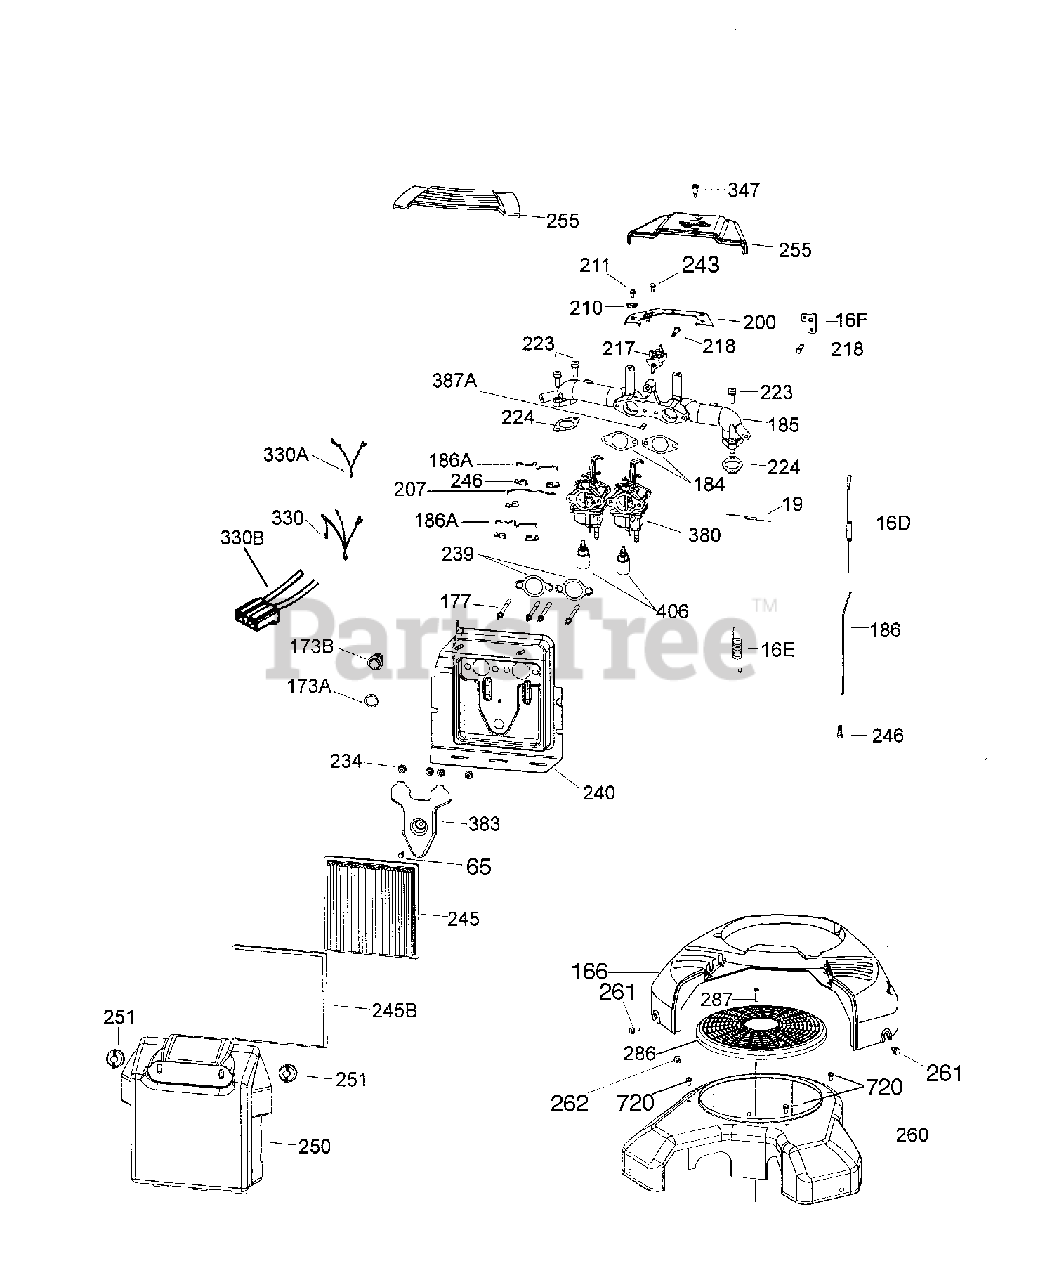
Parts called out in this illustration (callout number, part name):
11B	Screw, 10-32 x 7/16"
15B	Screw, 1/4-20 x 5/8"
16D	Governor Spring, Hi-speed
16E	Governor Idle Spring
16F	Bell Crank Lever
19	Throttle Spring
37	Lock Nut, 1/4-20
41	Piston & Pin Ass'y. (Std.) (Incl. 43)
41	Piston & Pin Ass'y.(.010"OS)(Incl.43)
72B	Oil Drain Plug
173A	Breather Tube Grommet
173B	Breather Tube Fitting
177	Carbuertor Mounting Stud
184	* Carburetor to Intake Pipe Gasket
185	Intake Pipe (Incl. 387A)
186	Governor Link
186A	Choke Link
200	Control Bracket
207	Throttle Link
210	Conduit Clip
211	Screw, 10-32 x 3/8"
217	Control Lever
218	Screw, 10-32 x 1-1/4"
223	Screw, T-30, 5/16-18 x 7/8"
224	* Intake Pipe Gasket (Pipe to Head)
234	Lock Nut, 1/4-20
238	Screw, 10-32 x 7/16"
239	* Air Cleaner Gasket
240	Air Cleaner Body Ass'y. (Incl. 239)
245	Air Cleaner Filter (Paper)
245B	Air Cleaner Pre-Filter (Poly)
246	Connector Bushing Link
250	Air Cleaner Cover
251	Wing Head Screw, 1/4-20 x 1-19/32"
255	Control Cover
260	Blower Housing (Red)
261	Screw, 1/4-20 x 1/2"
286	Flywheel Screen
287	Screw, T-20 8-18 x 1-15/32"
290	Fuel Line (16.75")
330	Fuel Solenoid Wire Assembly
330A	Fuel Solenoid Wire Assembly (Black)
342	Screw, 1/4-20 x 9/16"(Ref. 240 & 265)
347	Air Duct Mounting Stud
347	Screw, 10-32 x 27/32"
370A	Lubrication Decal
380	Carburetor (Incl. 184 & 428)
381	Screw, 8-32 x 27/64"
383	Carburetor Baffle
384	Screw, 10-24 x 9/16" Self Tap
387A	Roll Pin
406	Fuel Shut-Off Solenoid
477	Screw, T-30, 5/16-18 x 1 3/32"
